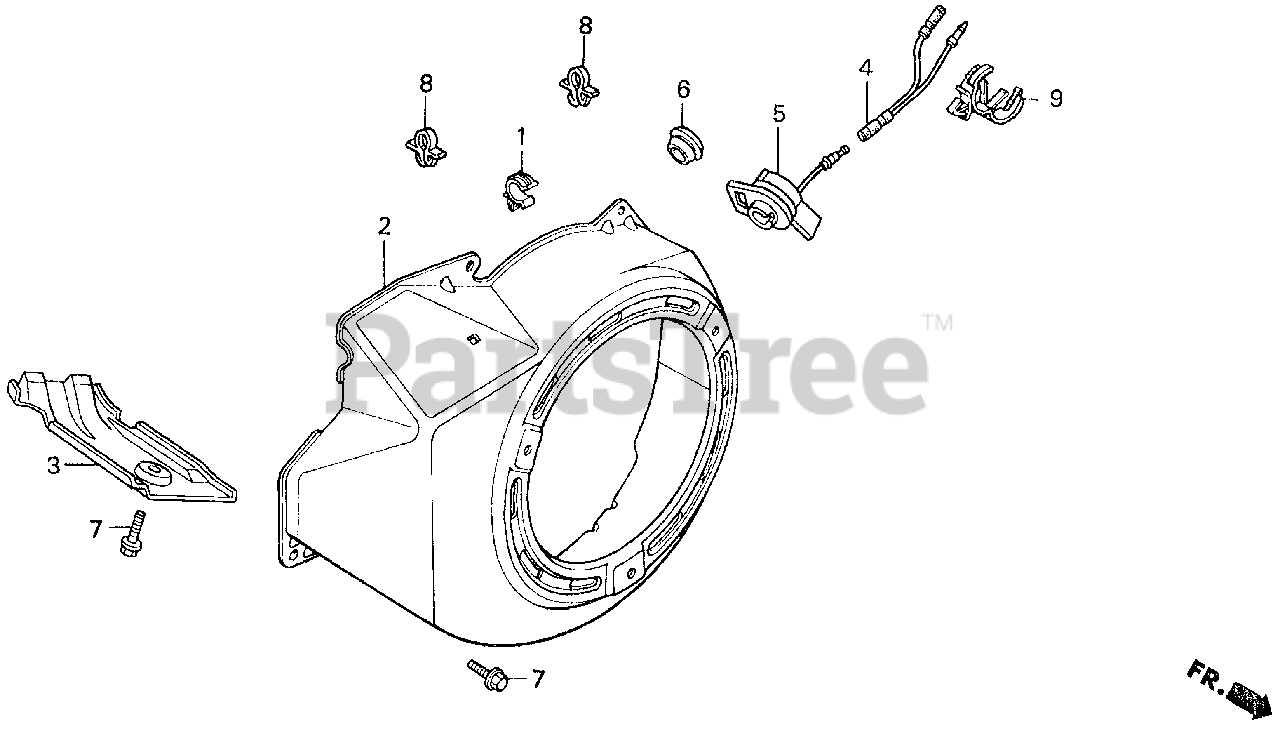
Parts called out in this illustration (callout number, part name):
2	COVER, FAN *T68* (TSURUI BLUE)
2	COVER, FAN *T80* (BAKERITE ORANGE)
3	SHROUD
4	SUB-HARNESS
6	GROMMET, DRAIN HOLE
7	BOLT, FLANGE (6X12) (CT200)
8	CLIP, WIRE HARNESS (6MM) (WHITE)
9	CLIP, WIRE HARNESS
